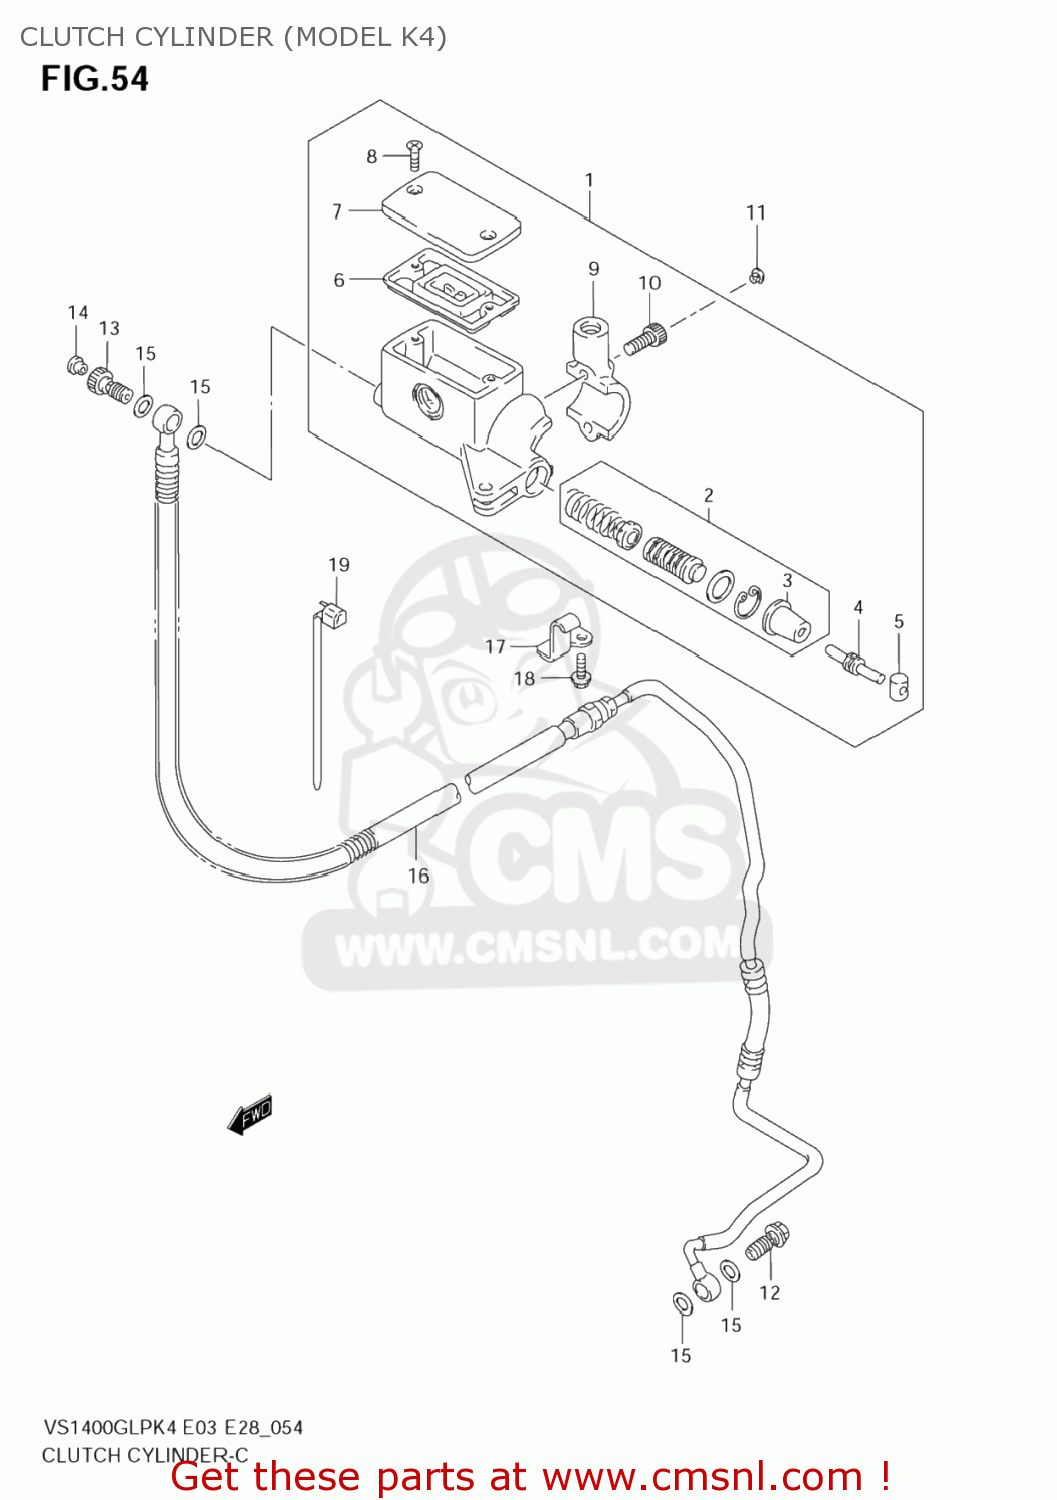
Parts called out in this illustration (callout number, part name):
1	CYLINDER ASSEMBLY,CLUTCH MASTER
2	PISTON & CUP SET
3	BOOT
4	PUSH ROD
5	BUSH
6	7
7	CAP
8	SCREW
9	HOLDER
10	BOLT
11	CAP(OD:10)
12	BOLT UNION
13	BOLT UNION
14	CAP(OD:12)
15	WASHER(10X15X1.5)
16	HOSE ASSY,CLUTCH
17	CLAMP,CLUTCH HOSE
18	BOLT
19	CLAMP(L:165)
